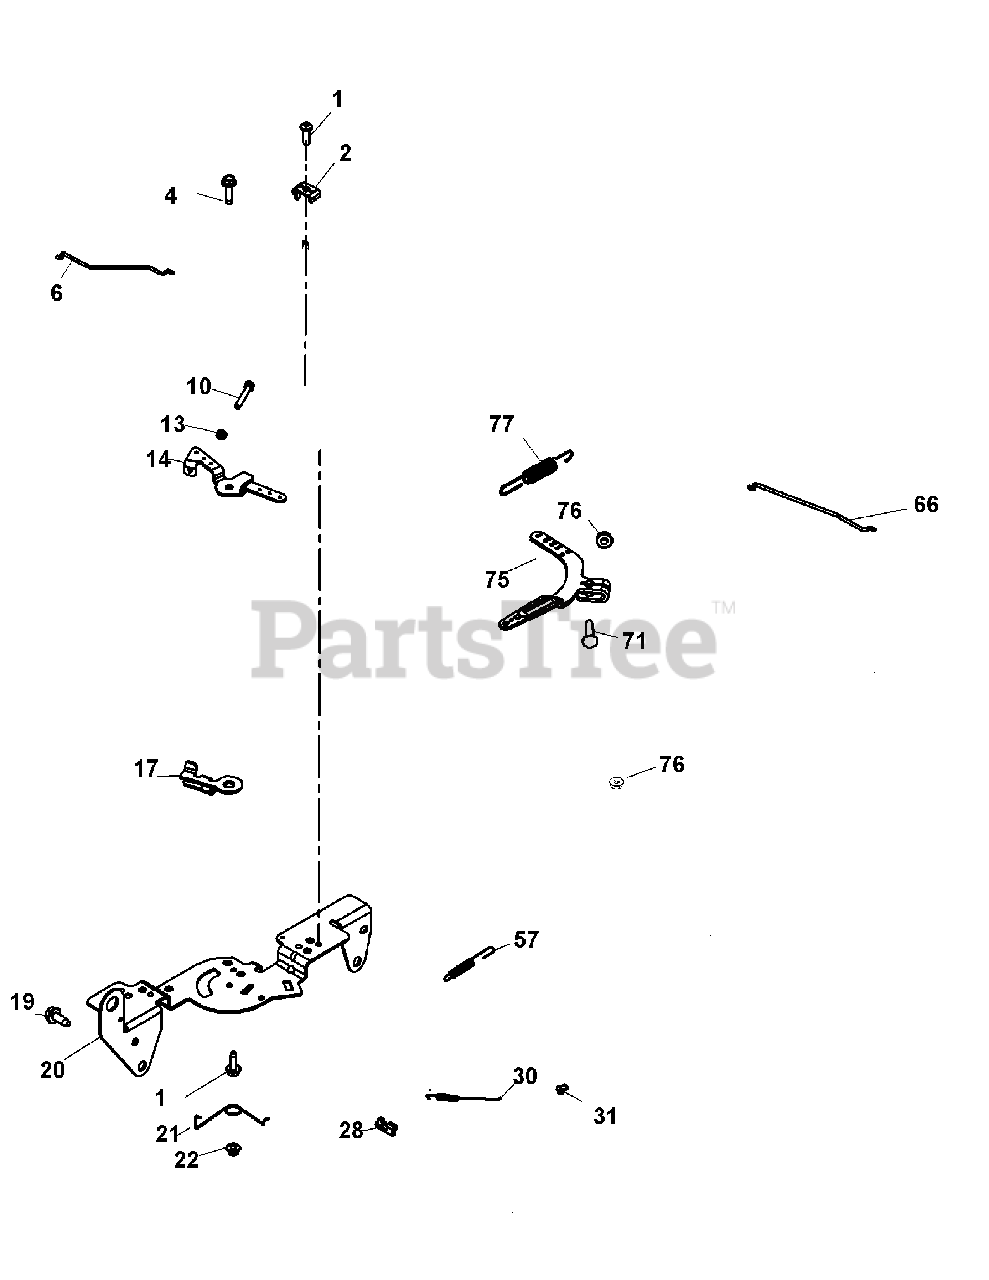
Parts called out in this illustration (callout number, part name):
1	Screw, Thread Forming
2	Clamp, Cable
4	Screw, Thread Forming
6	Linkage, Choke
10	Screw, Cap M4X.7X30
14	Spacer, Control Assy
17	Lever, Throttle Actuator
19	Screw, Thread Forming
20	Bracket, Control
21	Spring, Choke Return
22	Nut, Lock M5X.8
28	Bushing, Throttle Linkage
30	Spring, Linkage
31	Bushing, Linkage Retaining
57	Spring, Throttle Limiter
66	Linkage, Throttle
71	Bolt, Rd Hd Sq Neck M6X1.0X25
75	Lever, Governor
76	Nut, Flg M6X1.0
77	Spring, Governor (Purple)
